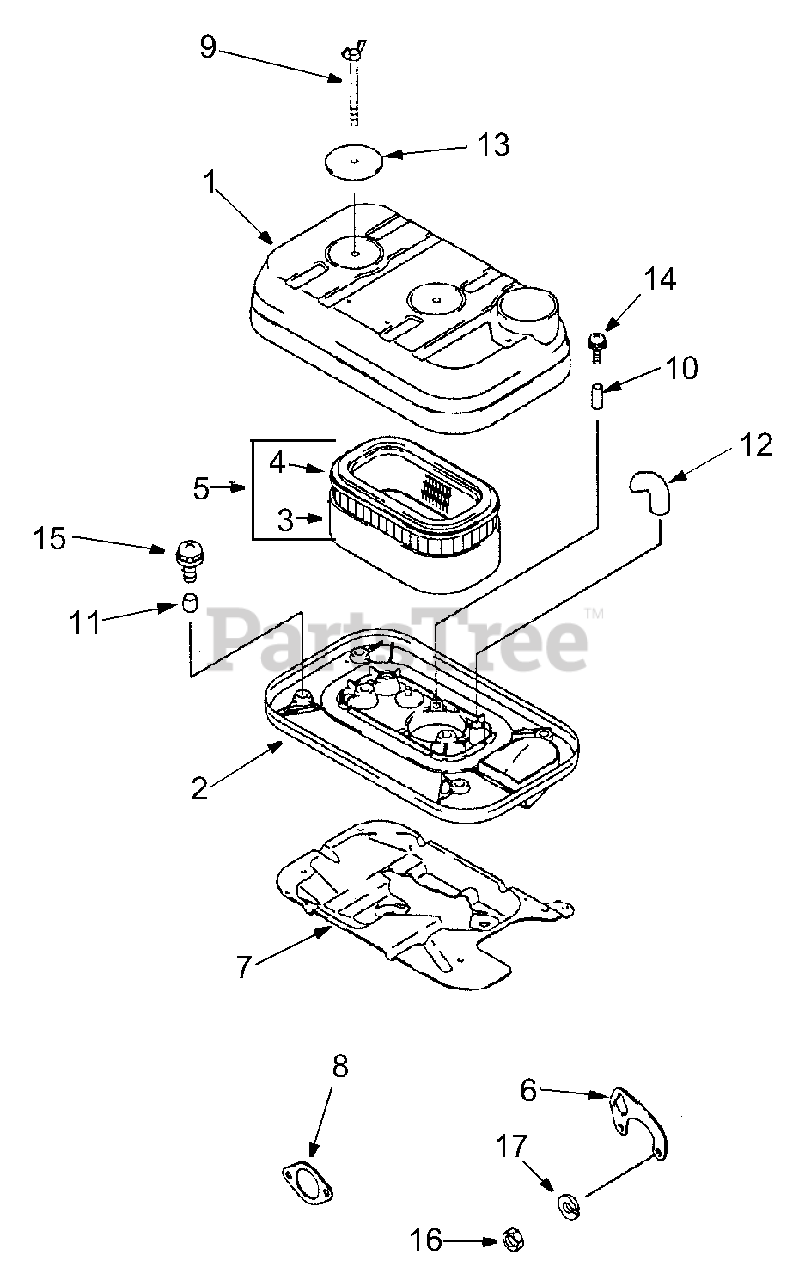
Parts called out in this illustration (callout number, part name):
1	Case, Air Filter
2	Base, Air Filter
3	Element, Foam
4	Element, Air Filter
5	Air Filter Ass'y
7	Bracket, Air Filter
8	Gasket, Muffler
10	Collar, 5.1 x 6.3 x 14
11	Collar, 6.2 x 7.8 x 7.5
14	Screw, Pan, WSP
16	Nut, Hex
17	Washer, Spring
